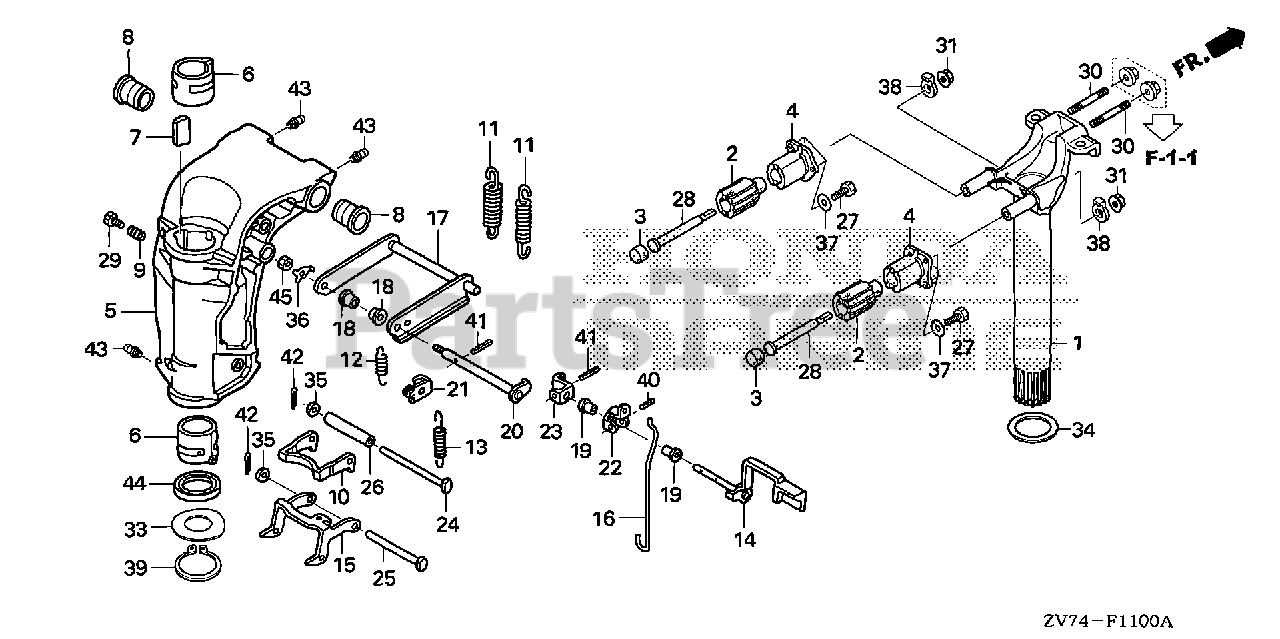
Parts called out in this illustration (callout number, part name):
1	FRAME, MOUNTING
2	RUBBER, MOUNTING (UPPER)
3	RUBBER, MOUNTING (UPPER) (B)
4	HOLDER, MOUNTING (UPPER) *NH282MU* (OYSTER SILVER METALLIC-U)
5	CASE, SWIVEL *NH282MU* (OYSTER SILVER METALLIC-U)
6	LINER, SWIVEL CASE
7	BLOCK, FRICTION
8	BUSH, SWIVEL CASE
9	SPRING, FRICTION ADJUSTING
10	HOOK, REVERSE LOCK
11	SPRING, REVERSE LOCK
12	SPRING, TILT LEVER
13	SPRING, TILT LINK
14	LEVER, TILT
15	ARM, REVERSE LOCK
16	ROD, RELEASE SWIVEL CASE
18	BUSH, TILT LEVER
19	BUSH, TILT LEVER
20	SHAFT, TILT
21	BRACKET, TILT SHAFT
22	BRACKET, RELEASE ROD
23	BRACKET, TILT LEVER
24	SHAFT, REVERSE LOCK (A)
25	SHAFT, REVERSE LOCK (B)
26	COLLAR, REVERSE LOCK
27	BOLT, HEX. (6X18)
28	BOLT, SPECIAL (10X130)
29	BOLT, SPECIAL (8X20)
30	BOLT, STUD (10X28)
31	NUT, FLANGE (10MM)
33	WASHER, WAVE (40MM)
34	WASHER, THRUST (34MM)
35	WASHER, PLAIN (6MM)
36	WASHER, LOCK
37	WASHER, PLAIN (6MM)
38	WASHER, SPECIAL
39	CIRCLIP (OUTER) (39MM)
40	PIN, SPRING (3.0X22)
41	PIN, SPRING (3.0X25)
42	PIN, SPLIT (2.0)
43	NIPPLE, GREASE
44	OIL SEAL (39.5X52X6) (ARAI)
45	NUT, HEX. (6MM)
